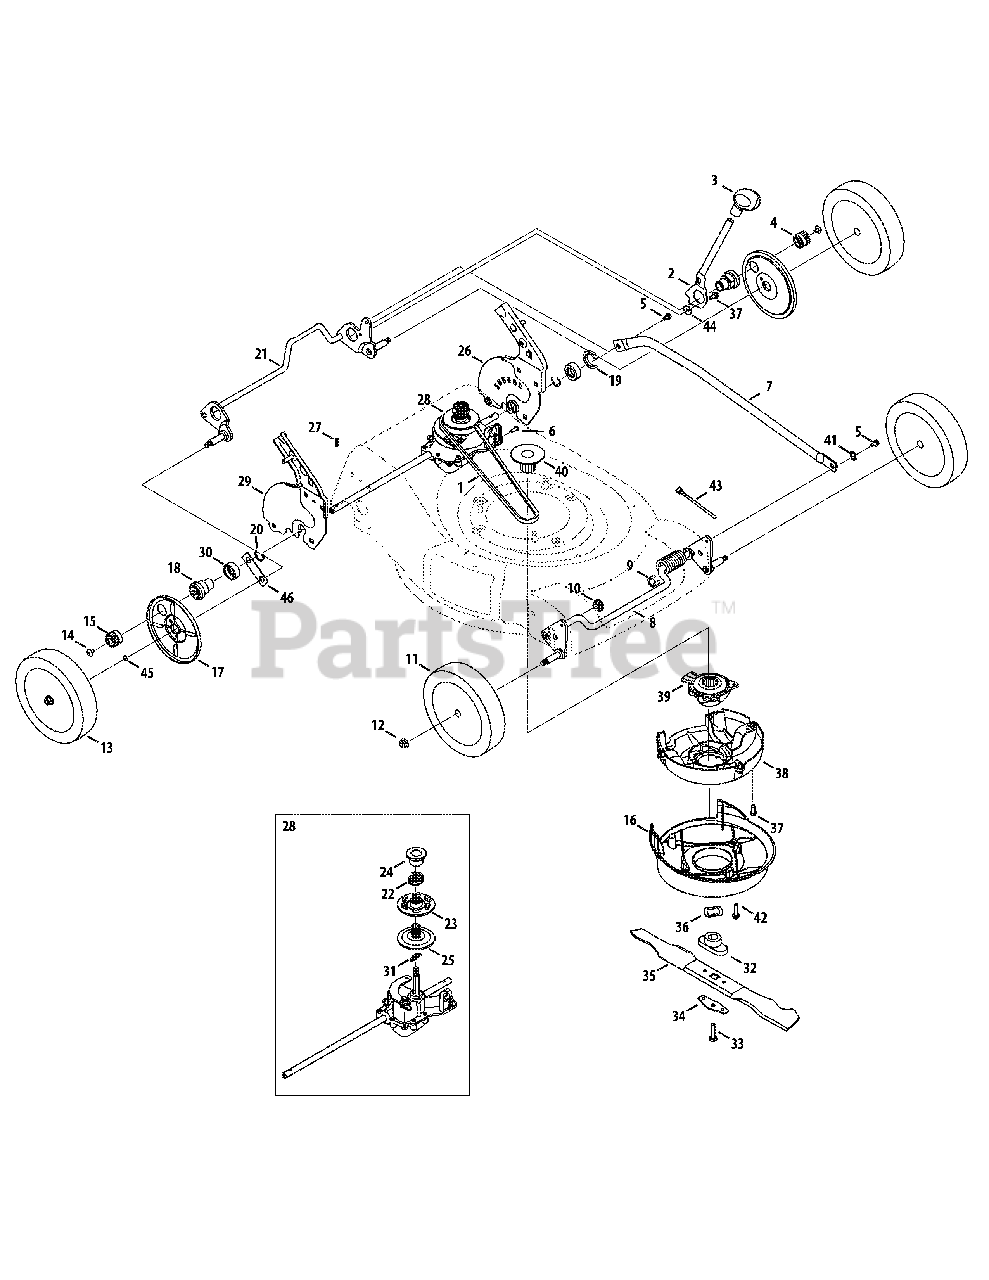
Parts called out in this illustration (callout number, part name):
1	V-Belt
2	Spring Lever
3	Foam Grip
4	Spur Gear, 14T - LH
5	Shldr. Screw, 1/4-20 x 0.50
6	Screw, #12-16
7	Cross Bracket
8	Front Bracket Assembly
9	Clip Spacer
10	Split Hex Flange Bearing
11	Front Wheel
12	Flange Lock Nut, 3/8-16
13	Rear Wheel
14	Screw, 1/4-20 x .39
15	Spur Gear, 14T - RH
16	Baffle
17	Wheel Dust Cover
18	Transmission Bearing Support
19	Clip Spacer
20	Retaining Ring .875
21	Rear Bracket Assembly
22	Compression Spring
23	Upper Pulley
24	Nut, Shldr.
25	Lower Pulley
26	Handle Bracket Assembly LH
27	Dowel Pin
28	Transmission Assembly
29	Handle Bracket Assembly RH
30	Bearing Support Spacer
31	Extension Spring
32	Blade Adapter
33	Screw, 3/8-24 x 1.50
34	Blade Bell Support
35	21" Mulching Blade
36	Washer, Wave, 1.5 x 1.0 x .029
37	TT Screw, 1/4-20 x .500
38	Engine Baffle
39	Lower Pulley Assembly
40	Pulley, Half
41	Washer, Wave, .390 x .625 x .016
42	Screw, 1/4-15 x 1.250
43	Cable Tie
44	Washer, Bell, .340 x .872 x .080
45	Ring, .375ID x .054
46	Gear Retainer Strap
